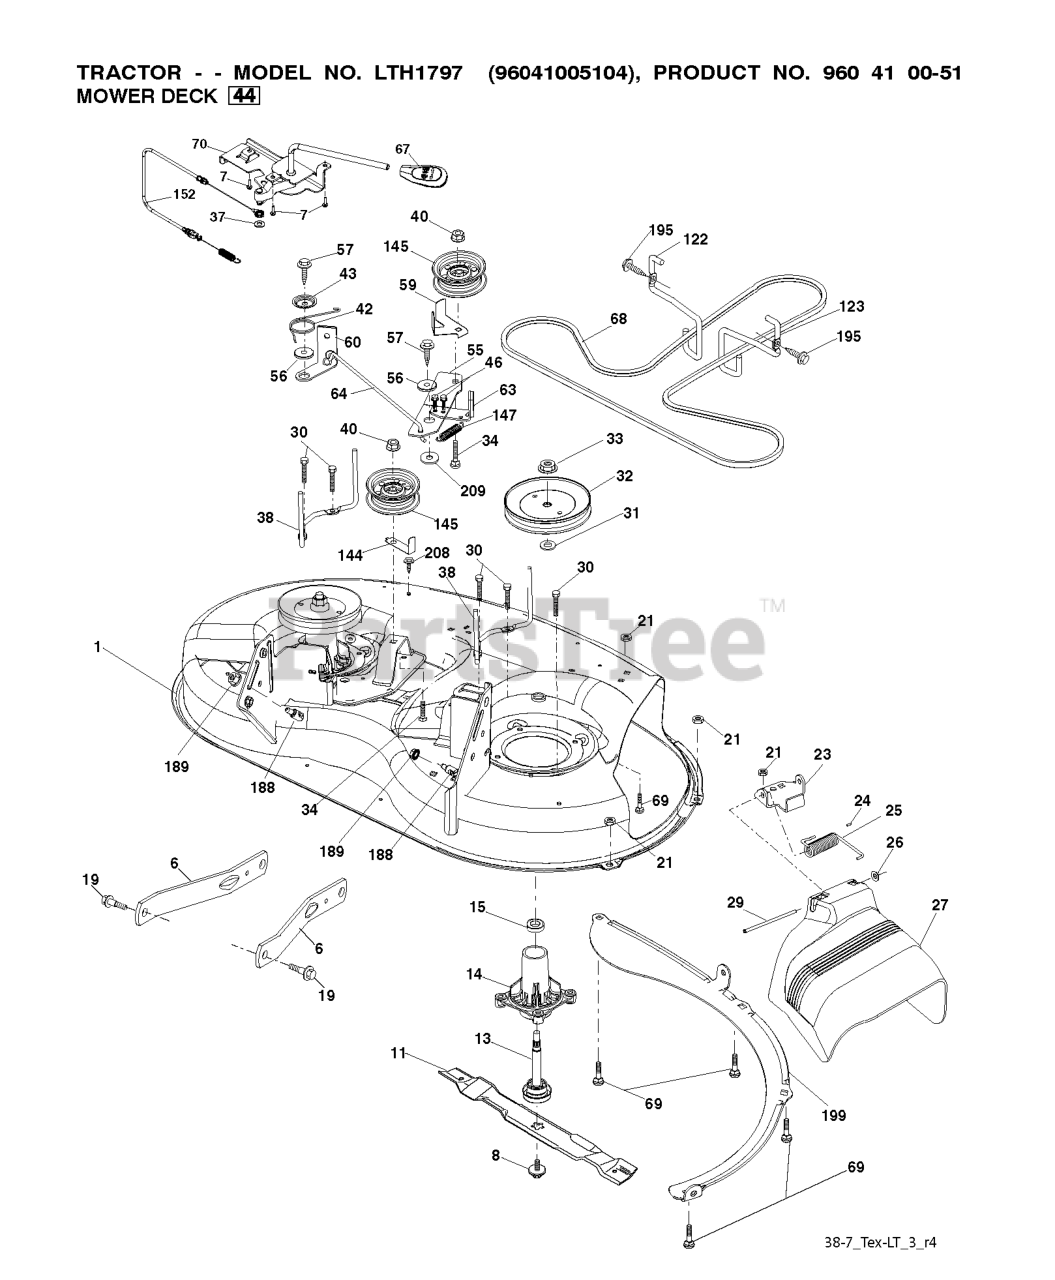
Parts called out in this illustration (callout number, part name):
1	HOUSING
6	ARM.SUSPENSION.MOWER.R
7	SCREW.#10 X 0.750.BOS
8	BOLT.WASHER.ASM.7/16-2
11	BLADE 38" PREMIUM
13	SHAFT.ASM.MDRL.N/GREASE.38
14	RP.HOUSING.MANDREL.4PT.
19	BOLT.SHOULDER
21	LOCKNUT
23	BRKT.DEFLECTOR.38"2005+
24	CAP-SLEEVE LT
25	SPRING.TORSION.DEFLECT
26	NUT PUSH M
27	SHIELD.DEFLECTOR.MWR.38-7/97CM
29	ROD.HINGE
30	SCREW, WASHER HEAD
31	WASHER.SPACER.MANDREL
32	PULLEY.MANDREL.5.0.PD.38"
33	NUT.FLANGE.LOCK.TOP
34	BOLT.3/8-16X1.50
37	WASHER
38	KEEPER BELT LH MANDREL
40	NUT LOCK FLG 3/8-16 UNC
42	SPRING.TORSION.BRAKE
43	SRPING.TORSION.RETAINE
46	SCREW.1/4-20X5/8
55	IDLER.ARM
56	SPACER.RETAINER
57	SCREW 3/8-16X1
59	GUARD, BELT
60	ARM BRAKE MOWER RH 38"
63	RP ARM.BRAKE.MOWER.38"LH.TEX
64	LINK BRAKE
67	HANDLE.CLUTCH.CABLE.LT
69	BOLT
70	CLUTCH.ASM.MANUAL.LT.PRED
122	KEEPER BELT ENGINE LH
123	KEEPER BELT RH
144	KEEPER BELT
145	PULLEY.IDLER.48"PRIMARY
147	SPRING RETURN
152	CLUTCH CABLE
188	STUD.FASTNER.W/ANTI-ROTATE
189	NUT LOCK HEX FLANGE 5/16-18
195	SCREW, 3/8-16X3/4
199	BAFFLE.VORTEX.FRONT.38"
208	SCREW 3/8-16X1/2
209	WASHER 12/32X2X10GA
